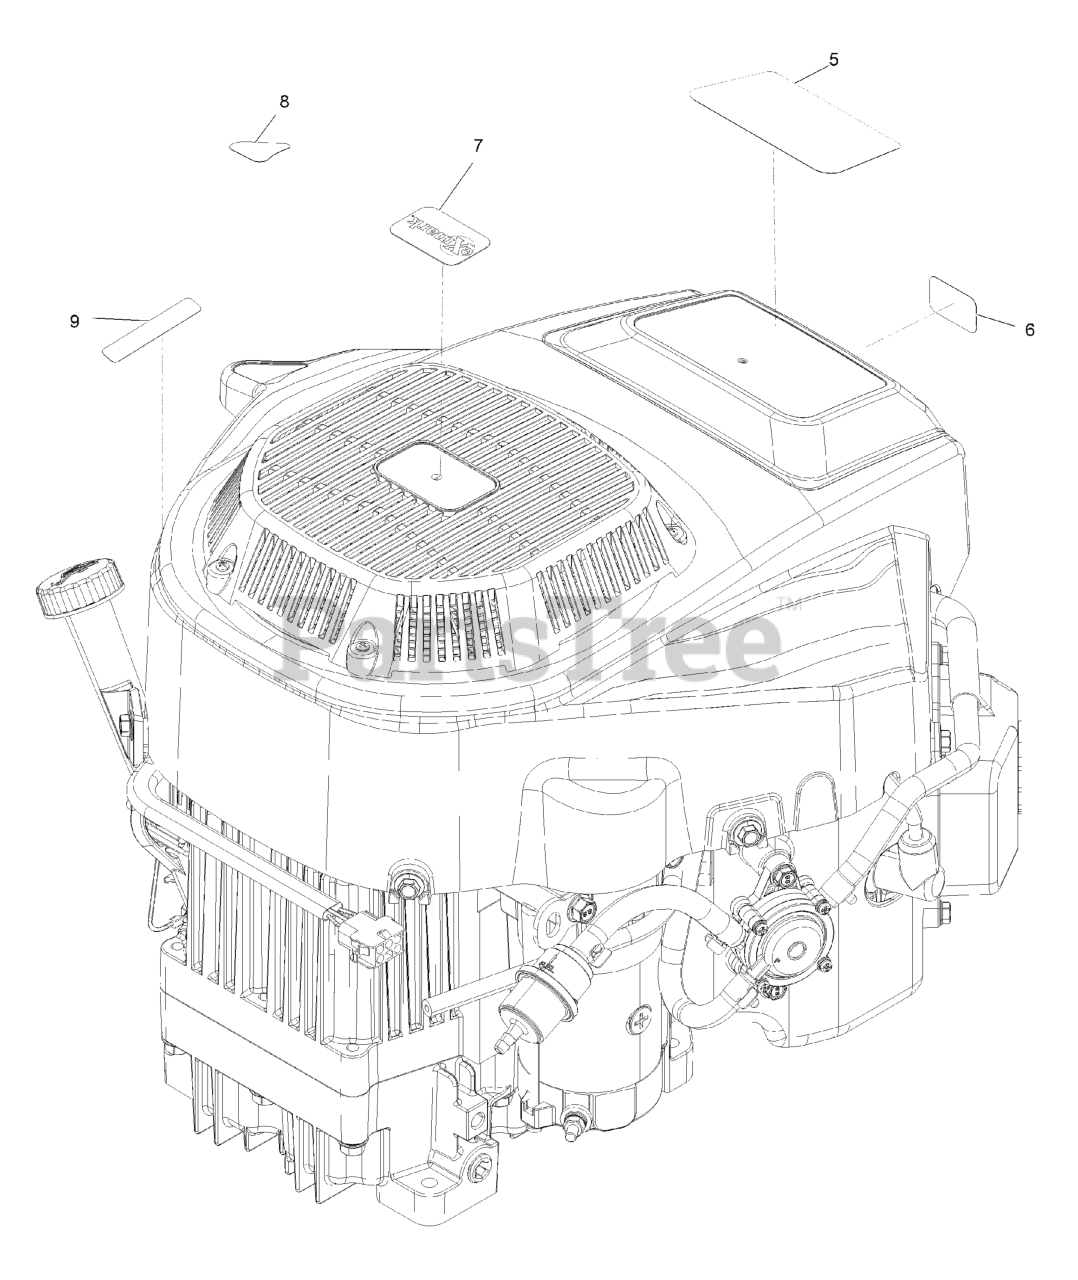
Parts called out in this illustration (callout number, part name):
5	Decal-Engine 702 V-Twin Exmark
6	PLACARD-INTAKE, EXMARK
8	DECAL-DRAIN, OIL
9	DECAL-SHUTDOWN
